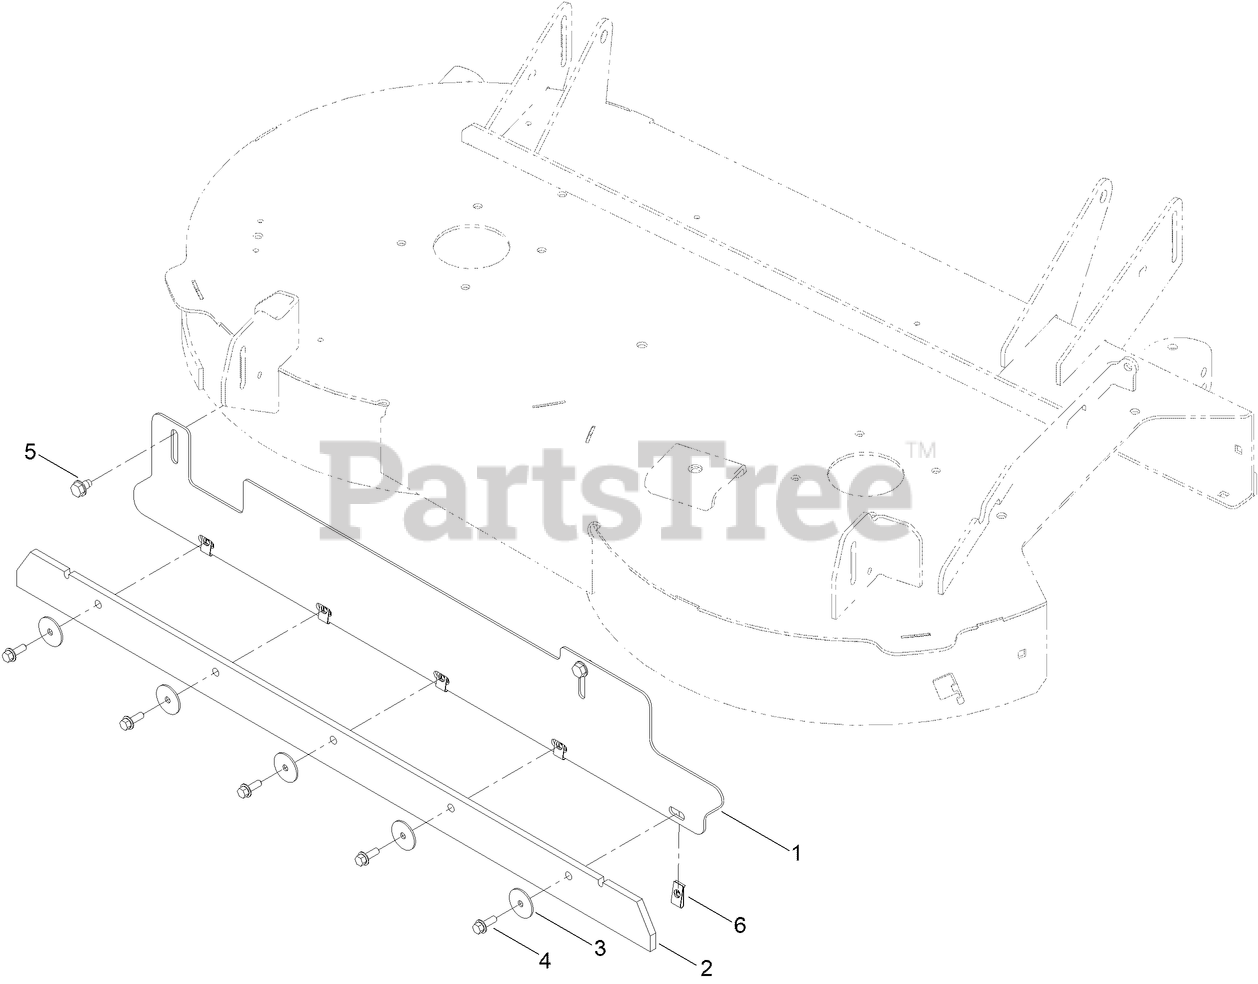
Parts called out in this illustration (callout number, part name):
1	BRACKET-STRIPING, 42"
3	WASHER-FLAT
4	SCREW-HHF
5	SCREW-HWH, THD ROLL
6	NUT-SPEED
